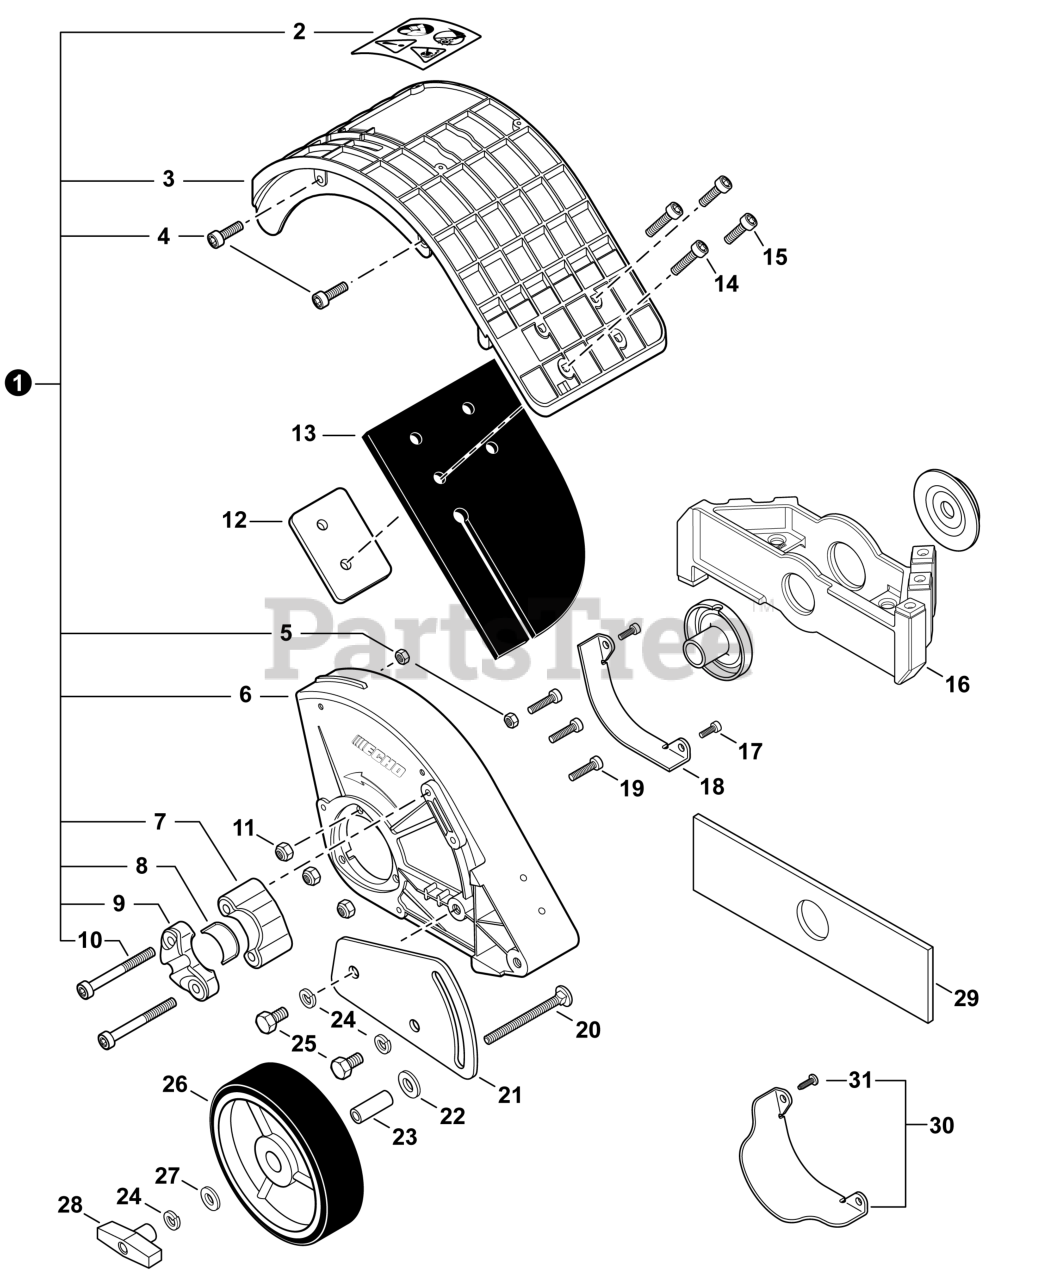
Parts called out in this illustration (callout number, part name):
1	BED REDEFINER KIT
2	LABEL - CAUTION
3	SHIELD, DEBRIS
4	BOLT, TORX 4x12
5	NUT, LOCK 4
6	SHIELD, BLADE
7	BRACKET - INNER
8	PAD, FOAM
9	BRACKET - OUTER
10	SCREW - 6x35
11	NUT, LOCK M5
12	PLATE, FLAP
13	FLAP, DEBRIS
14	BOLT, TORX 4x16
15	BOLT, TORX 4x12
16	BLADE, REDEFINER
17	BOLT, TORX 4x12
18	GUARD, SHIELD
19	BOLT, TORX 5x20
20	BOLT 5/16"-18x2-1/2"
21	BRACKET, WHEEL
22	WASHER M10
23	COLLAR 12
24	WASHER, SPRING 8
25	BOLT 8x14
27	WASHER 8
28	KNOB, FASTENER
29	BLADE - 2 PK
30	GUARD KIT, SHIELD
31	SCREW 4x12
